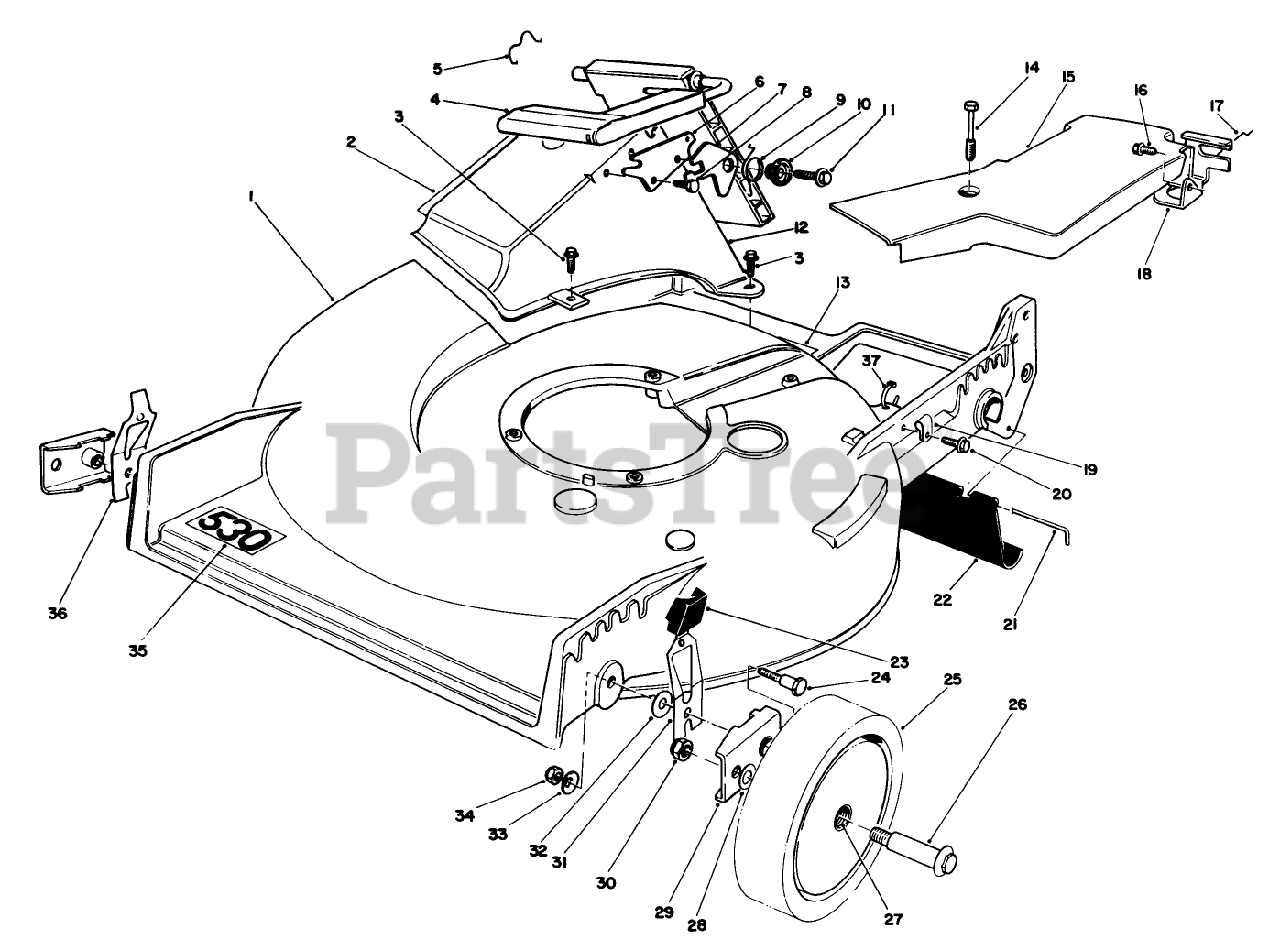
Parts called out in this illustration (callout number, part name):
1	21 SP RB HSG/DECAL
3	SCREW-HWH
5	DOOR RET SPRING
6	DOOR LATCH PLATE
7	SAFETY LATCH
8	SCREW-PLASTITE
9	TORSION SPRING
10	DOOR SPACER
11	SCREW-HWH
14	SCREW-HWH
16	SCREW-THD ROLL, HWH
17	RETAINER-CABLE
19	CLAMP-CABLE
20	SCREW
21	ROD-SHIELD
23	KNOB-ARM
24	PIVOT SCREW
26	BOLT-WHEEL
27	BUSHING
28	WASHER
29	HP PIVOT ARM ASM
32	WASHER-PIVOT
33	WASHER-BELLEVILLE
34	NUT-LOCK, NI
37	TIE-CABLE
